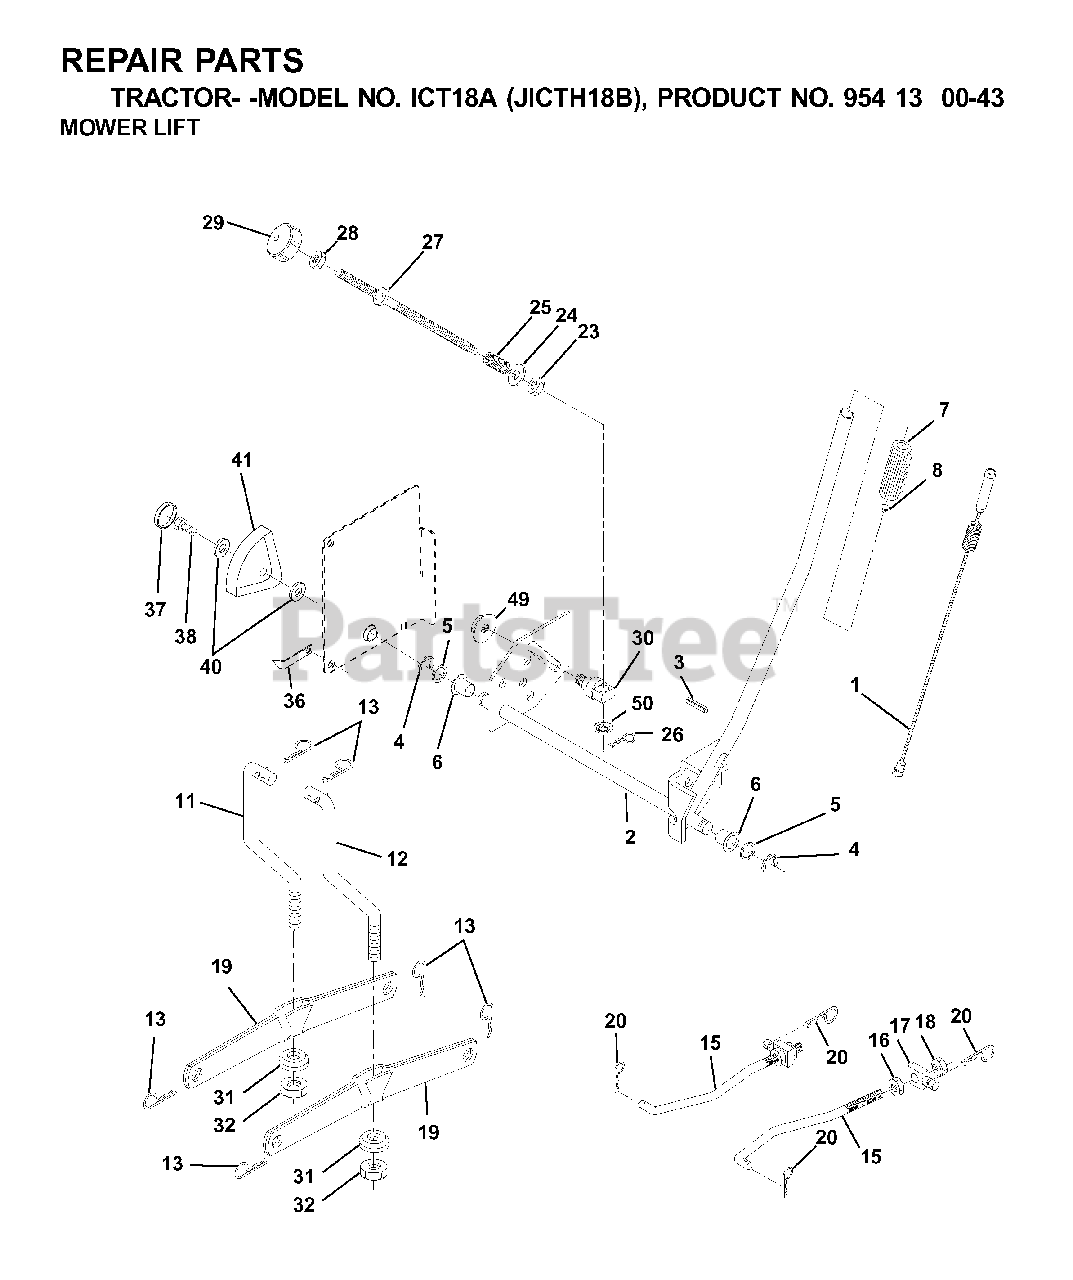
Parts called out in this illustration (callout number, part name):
1	WIRE ASM INNER W/ PLUNGER LT
2	SHAFT ASM R HANDLE
3	PIN GROOVE
4	RETAINING RING LT
6	BEARING.NYLON
7	GRIP HANDLE
8	PLUNGER BUT KIT
11	LINK
12	LINK
13	RETAINER-SPRNG RB
15	LINK.SUSPENSION.FRONT
16	NUT
17	TRUNION
18	NUT
19	ARM.REAR.SUSPENSION
20	SPRING RETAINER
25	SPRING**
26	RETAINER CLIP
27	ROD ADJ LIFT
28	NUT
29	KNOB INF 3/8-16
31	BEARING.PIVOT.LIFT
32	NUT CROWNLOCK 3/8-24
36	POINTER, HEIGHT INDICATOR
37	PLUG,HOLE
38	SCREW 5/16-18X1
41	HEIGHT INDICATOR
49	NUT
50	NUT PUSH M
